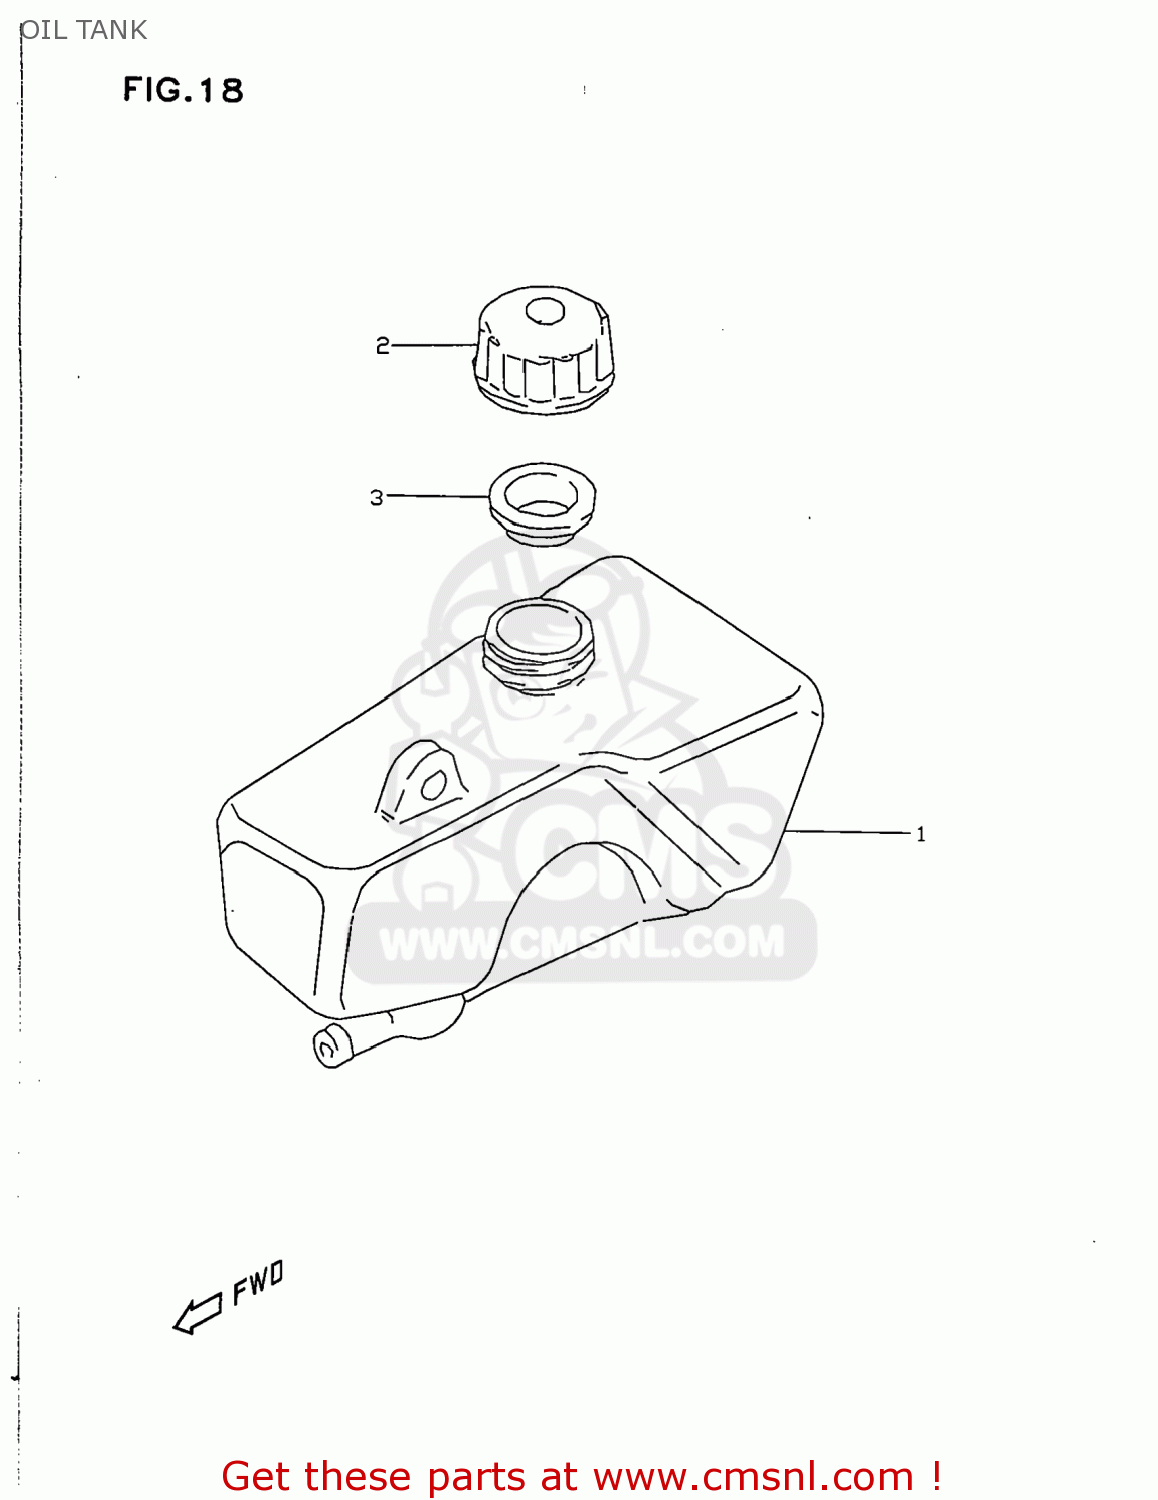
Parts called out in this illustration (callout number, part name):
1	TANK,OIL
2	CAP,OIL TANK FILLER
3	GASKET,OIL TANK (NAS)
